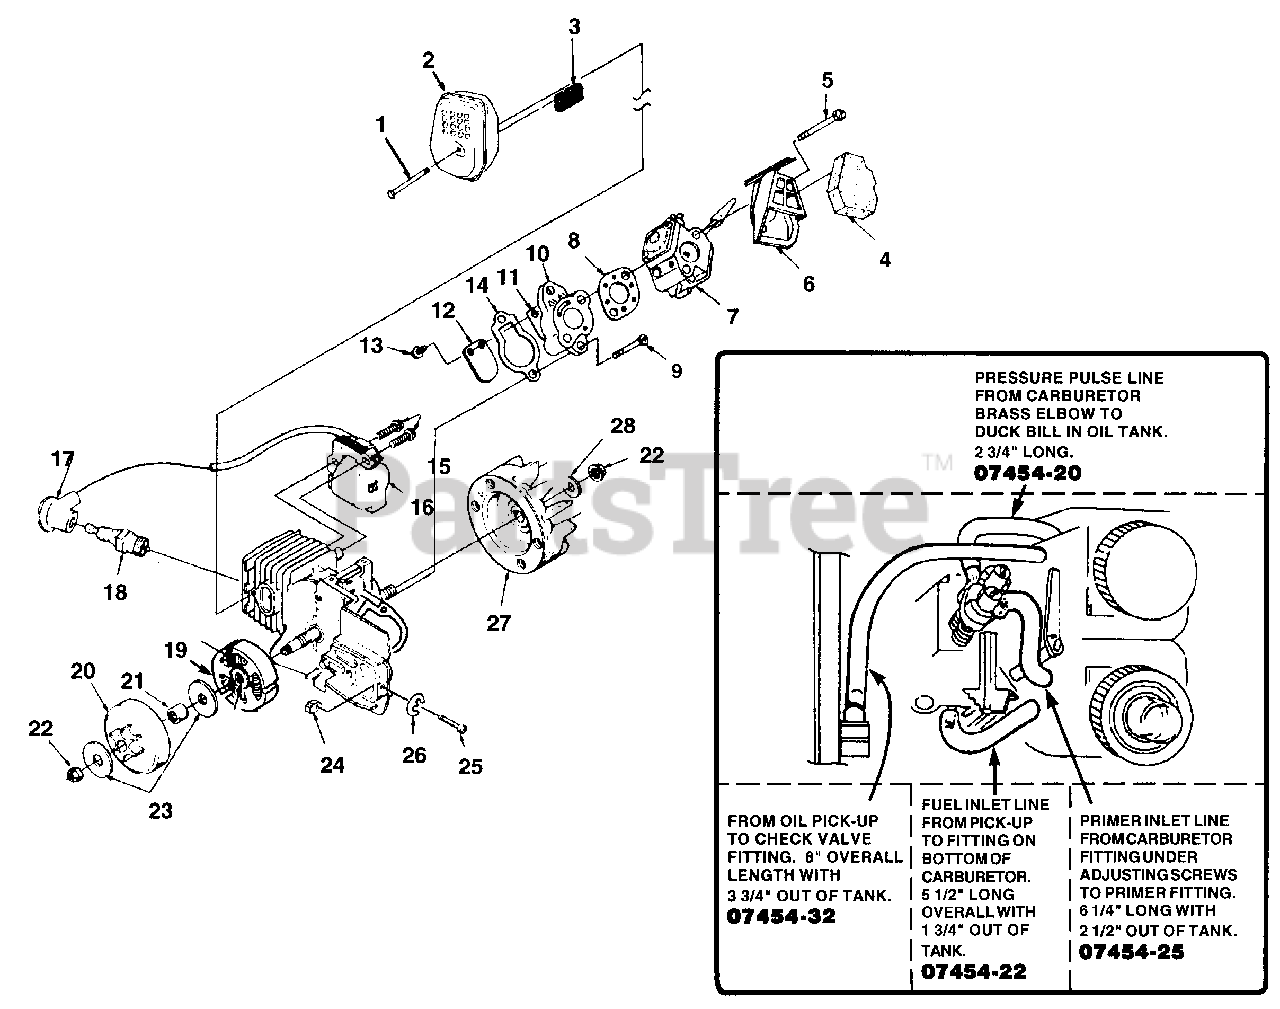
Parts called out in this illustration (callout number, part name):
1	SCREW - Machine Hex Sems (#8-32 X 3/4")
2	MUFFLER
3	SCREEN - Spark Arrestor
4	FILTER - Air
5	SCREW - Thread Forming
6	BOX - Air Filter
7	CARBURETOR (Zama)
8	GASKET - Carburetor
9	SCREW - Plastite, (10-14 X 1")
10	HEAT DAM
11	REED
12	STOP - Reed
13	SCREW - Hex Taptite (4-40 X 3/8")
14	GASKET - Intake Manifold
15	SCREW - Thread Forming (8-32 X 1")
16	MODULE - Ignition
17	TERMINAL
18	SPARK PLUG (Champion DJ7Y)
19	CLUTCH KIT
20	SPROCKET & DRUM
21	BEARING
22	NUT - Rotor (5/16-24)
23	WASHER - Thrust
24	PIN - Adjusting
25	SCREW & E-RING KIT
26	E-RING
27	ROTOR & STARTER PAWL
28	WASHER - 5/16"
0745420	PRESSURE PULSE LINE
0745422	FUEL INLET LINE
0745425	PRIMER INLET LINE
0745432	LINE - (8")
